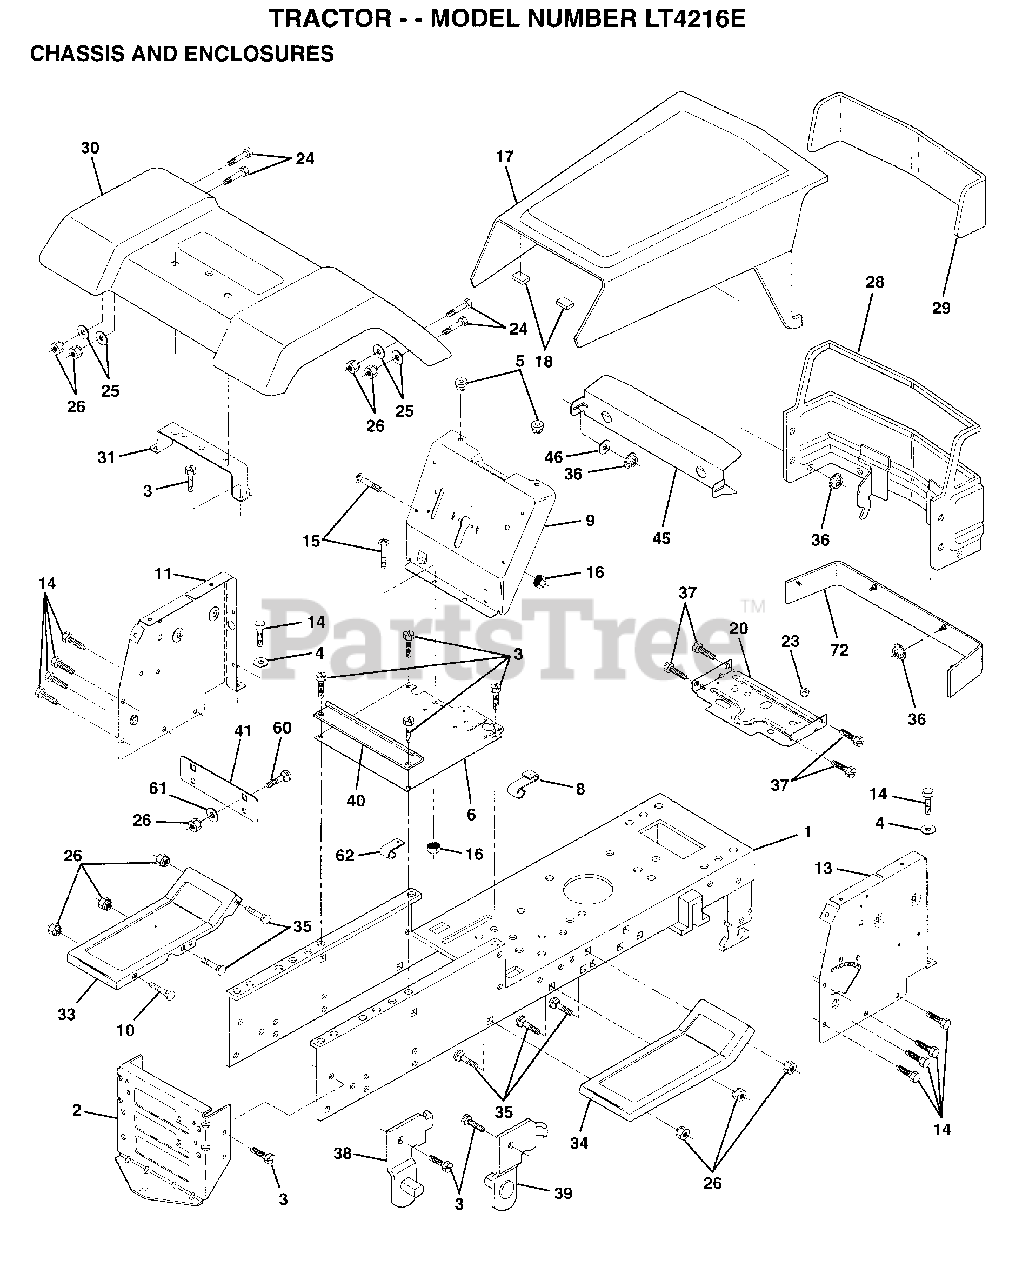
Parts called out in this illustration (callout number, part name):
1	CHASSIS.WLD.11GA
3	SCREW
4	WASHER
8	"CLIP,INSULATOR"
11	PANEL.DASH.LH.
12	CLIP.TINNERMAN
13	PANEL.DASH.RH
14	SCREW LT
20	PLATE.MTG.BTRY.TK
23	BUSHING SNAP NL BLK FUEL LINE
24	BOLT
25	WASHER
26	NUT
28	GRILL QUADRA
29	LENS QUADRA
31	BRACKET SUPT FEND
33	FOOTREST.LH.LT/GT
34	FOOTREST.RH.LT/GT
35	BOLT
37	SCREW LT
38	BRACKET ASM LH
39	BRACKET ASM RH
40	SPACER FENDER LT
41	PLATE EXTEN FEND
48	RIVET.PUSH.PLATE
49	SCREW HEX CRT
50	BRACE SUPT DASH
51	NUT
52	WASHER 9/32X7/8X 16 GA
53	BRACKET.GRILLE.LH
55	BRACKET.GRILLE.RH
58	DUCT.AIR.B&S.18HP
60	BOLT
61	WASHER
68	NUT
